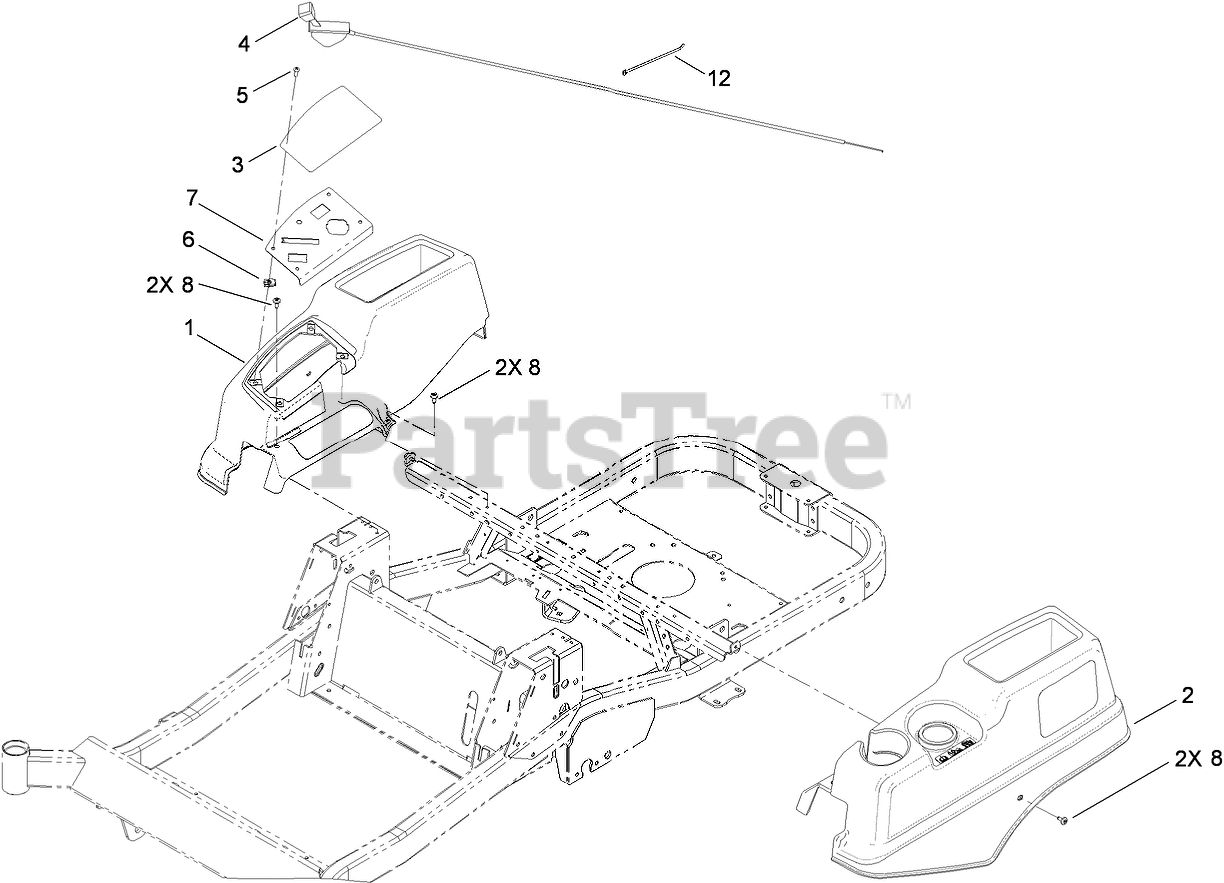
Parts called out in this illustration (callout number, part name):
1	POD-RH
2	POD-LH
3	DECAL-PANEL, CONTROL
4	CABLE-THROTTLE
5	SCREW-PRH
7	PANEL-CONTROL
8	SCREW-SHOULDER
12	TIE-CABLE
